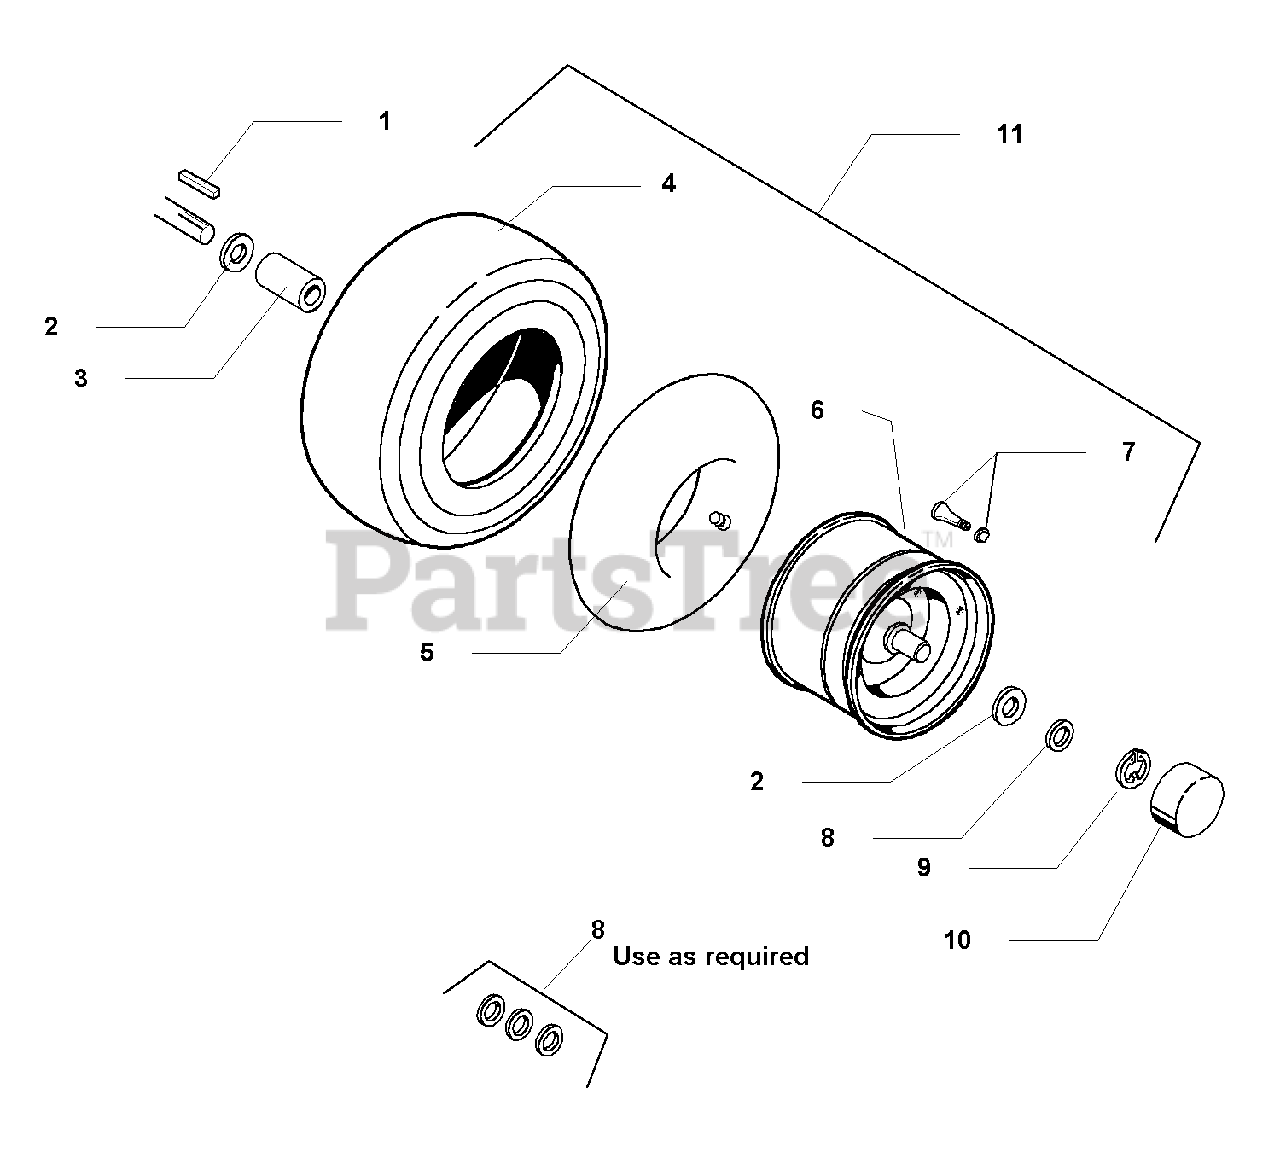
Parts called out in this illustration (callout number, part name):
1	KEY
4	TIRE, 20 x 8.00-8
5	TUBE (Service only)
6	WHEEL ASSEMBLY, 20 x 8.00-8
7	VALVE STEM & CAP
8	WASHER, Optional (Use as Required)
11	WHEEL & TIRE ASSEMBLY, 20 x 10.00-8 (Includes Ref. Nos. 4, 6 & 7)
